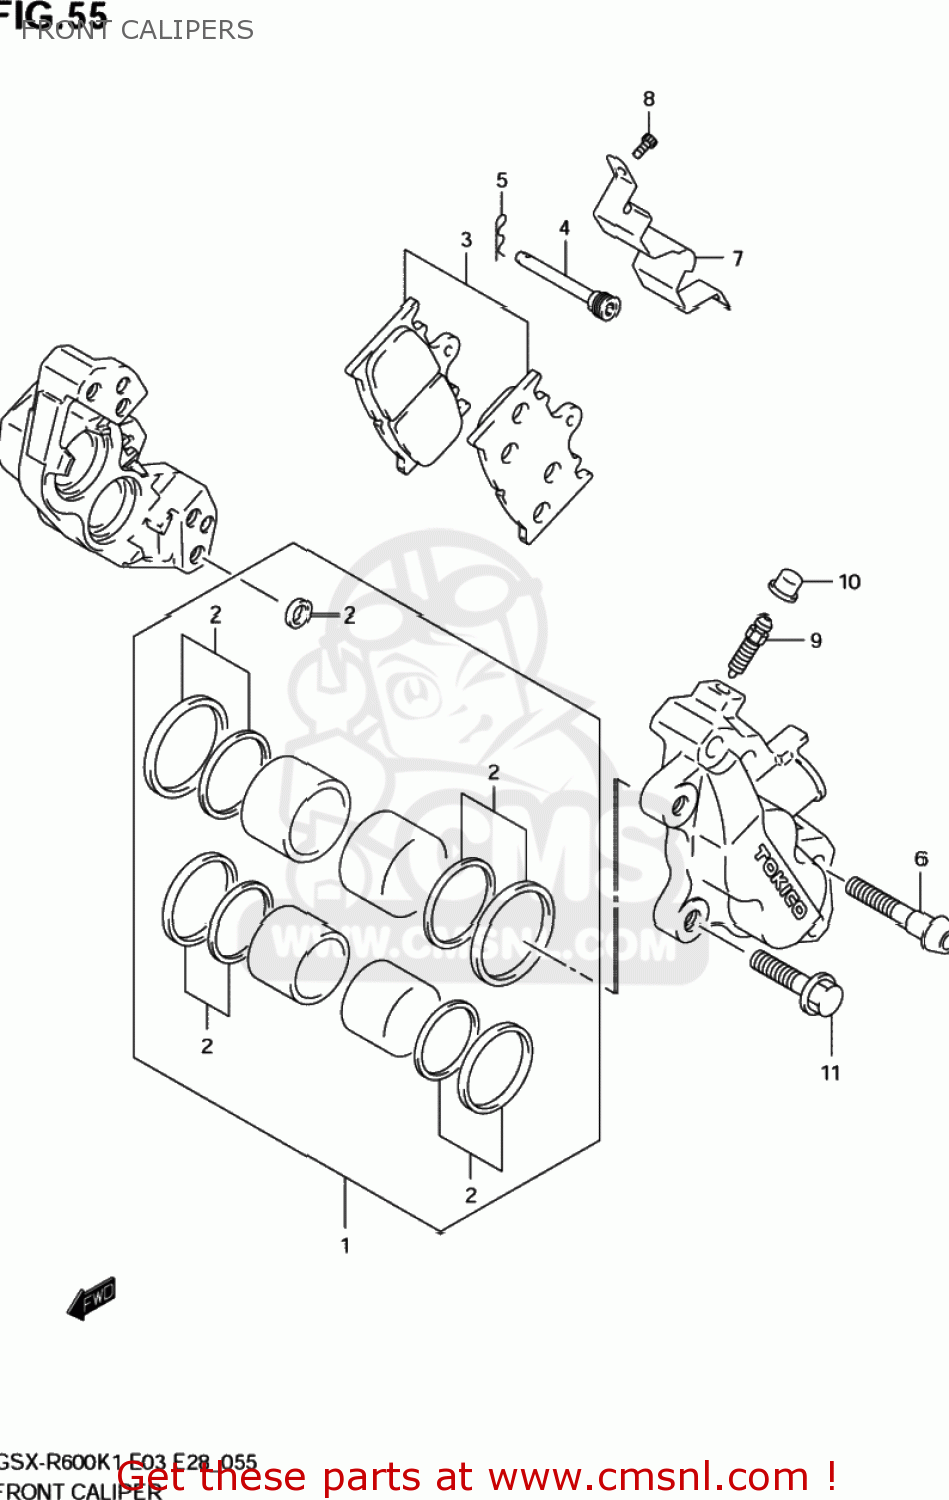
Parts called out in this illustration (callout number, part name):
1	PISTON SET
2	SEAL SET,PISTON
3	PAD,SET
4	PIN,PAD
5	CLIP,PAD PIN
6	BOLT
7	COVER,CALIPER DUST
8	SCREW
9	BLEEDER
10	CAP,BLEEDER PLUG
11	BOLT(8X28)
